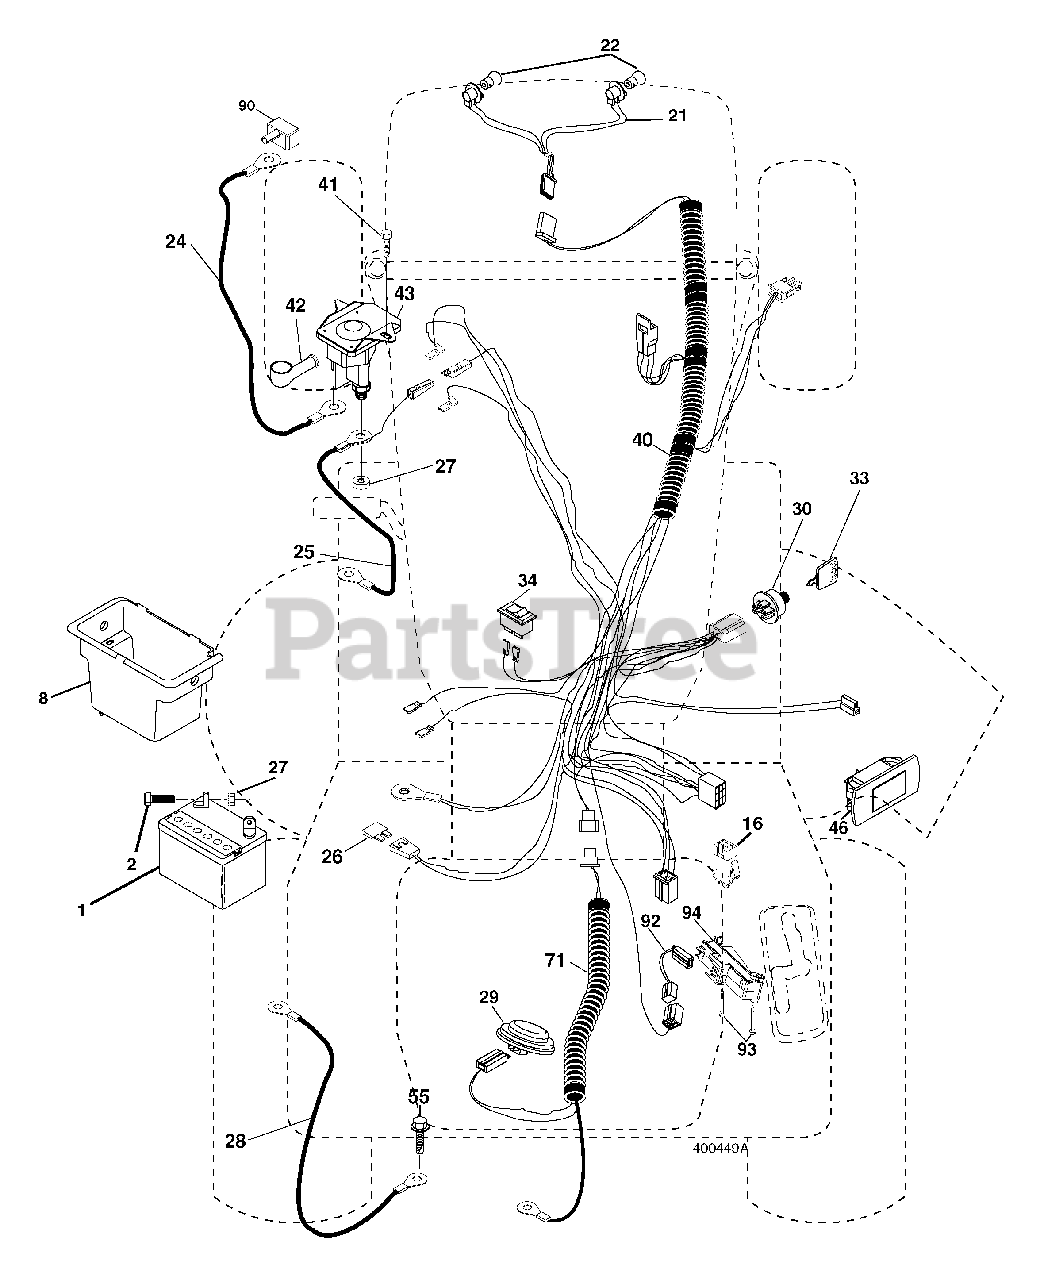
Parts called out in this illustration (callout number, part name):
1	Battery
2	Bolt Hex Head 1/4-20 x 3/4
8	Box Battery
16	Switch Interlock Push-In
21	Harness Socket Light W/4152J
22	Bulb Light
25	Cable Starter
26	Fuse
27	Nut Keps Hex 1/4-20 unc
28	Cable, Ground
29	Switch, Seat
30	Switch, Ignition
33	Key, Ignition
34	Switch Light / Reset
40	Harness Ignition
41	Screw Thd Cut 1/4-20 x 1/2
42	Cover, Terminal
43	Solenoid
46	Gauge Servicereminder Hrmtr Rect.
55	Screw Thdrol 5/16-18 x 3/4 TYTT
71	Harness Ignition Dash
90	Cover Terminal Battery
